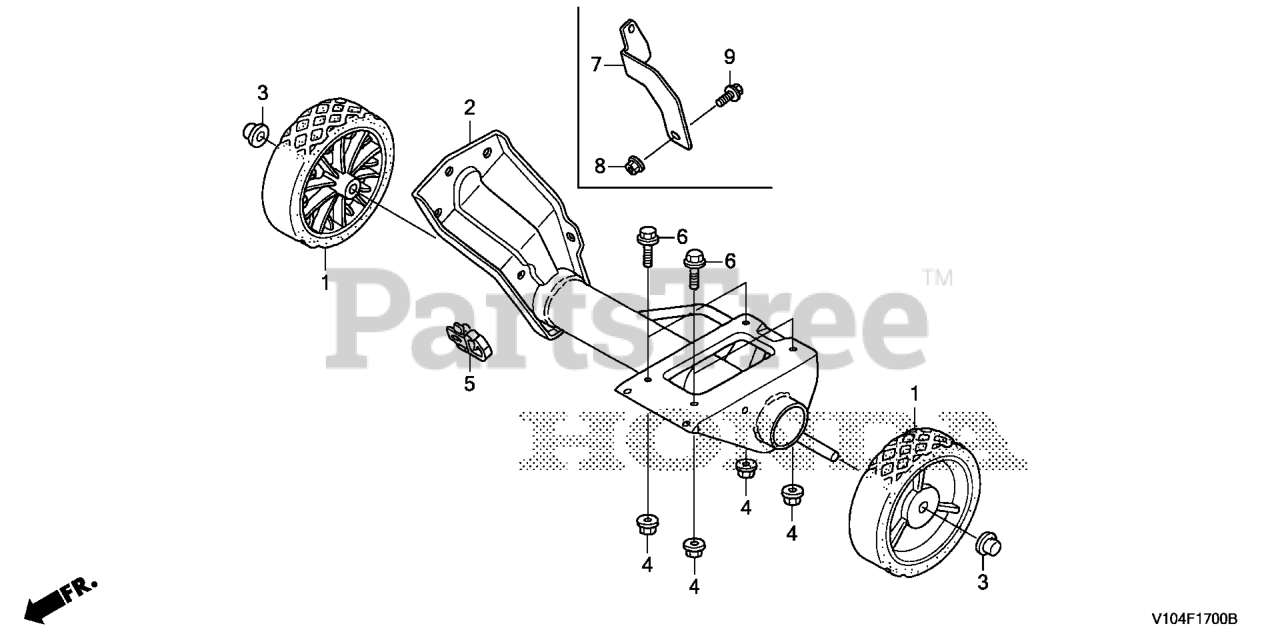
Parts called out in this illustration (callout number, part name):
1	WHEEL ASSY. *NH164* (GRIP GRAY)
1	WHEEL ASSY. *R280* (POWER RED)
2	BED, ENGINE
3	NUT, PUSH (12.7MM)
4	NUT, FLANGE (8MM)
5	CLIP, WIRE HARNESS
6	BOLT, FLANGE (8X35)
